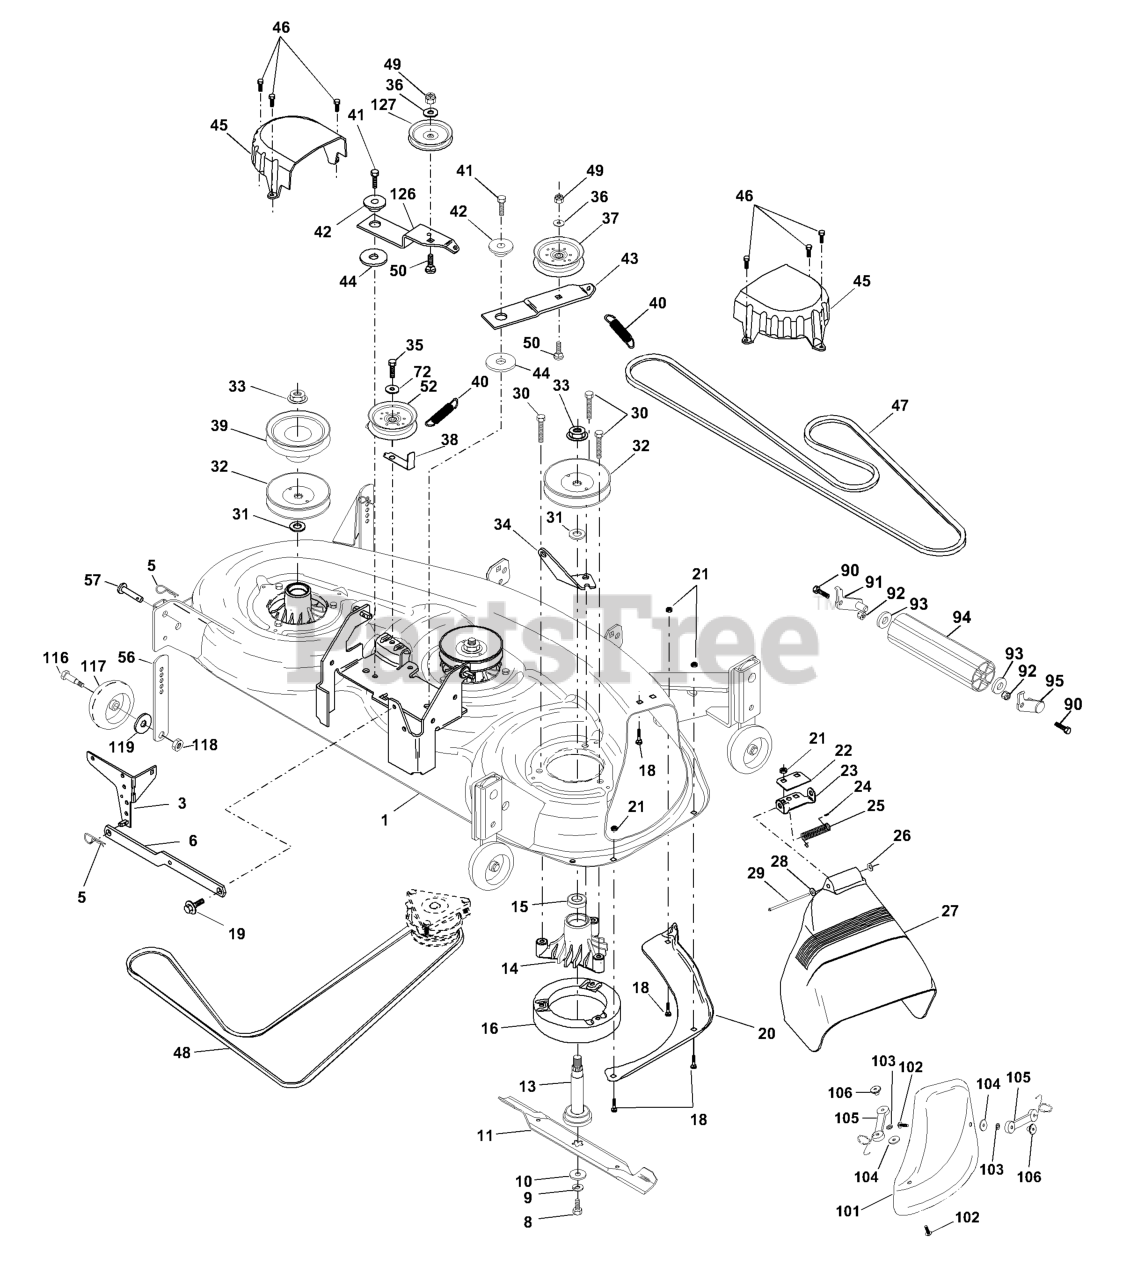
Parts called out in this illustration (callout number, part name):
1	DECK SVC W/ADJ.GWB.46"
3	BRACKET SWAY BAR
5	RETAINER-SPRNG RB
6	REAR SUSP ARM
8	BLADE BOLT
9	LOCKWASHER
10	WASHER.BLADE
11	BLADE.46".HI-LIFT.PREMIUM
11	MULCH BLADE 46"
13	SHAFT.ASM.W/BEARING
14	HOUSING.MANDREL.44/46" VENT
16	STRIPPER.MANDREL.ROUND.BLACK
18	BOLT
19	BOLT SHD 5/16-18
20	BAFFLE, VORTEX MOWER 46"
21	LOCKNUT
22	BRKT, STIFF 42" DECK
23	BRKT, DEFLECTOR MOWER 42"
24	CAP-SLEEVE LT
25	TORSION SPRING
26	NUT PUSH M
27	SHIELD DEFLECTOR
28	Washer 11/32 x 5/8 x 16 Ga.
29	ROD.HINGE
30	SCREW THDROL ROLLING WASHER HD
31	WASHER
32	MANDREL PULLEY
33	NUT
34	ANCHOR SPRING, DECK 46"
35	SCREW LT
36	WASHER
37	PULLEY.IDLER.FLAT
38	REPL BY 532 1560-86
39	REPL BY 532 1449-17
40	SPRING.SEC.44"VEN
41	SCREW.3/8-16
42	SPACER RETAINER
43	ARM, IDLER, SECONDARY
44	HARDENED WASHER
45	COVER MANDREL 46
46	SCREW.1/4-20X5/8
47	BELT V SECONDARY
48	V-BELT PRIMARY 50"
50	BOLT.3/8-16X1.50
52	PULLEY.IDLER.FLAT.46".PRIMARY
56	BAR.ADJUST.WHEEL.ANTI.SCALP.BL
57	RIVET.PIN.HEAD.YELLOW.
72	WASHER
90	BOLT
91	BRACKET LH (A)
92	NUT
93	Washer 17/32 x 7/8 x 16 Ga.
94	NOSE ROLLER
95	BRACKET RH (B)
101	COVER.MULCH.46"3-BLADE.(2 2)
102	SCREW
103	LOCKWASHER #10
105	LATCH ASSY
106	WELDNUT
116	BOLT, SHOULDER
117	WHEEL GAGE DONUT
118	LOCKNUT
119	WASHER.5/16.FLAT.STE.STD.
126	ARM, IDLER PRIMARY DECK
127	REPL BY 532 1467-63
